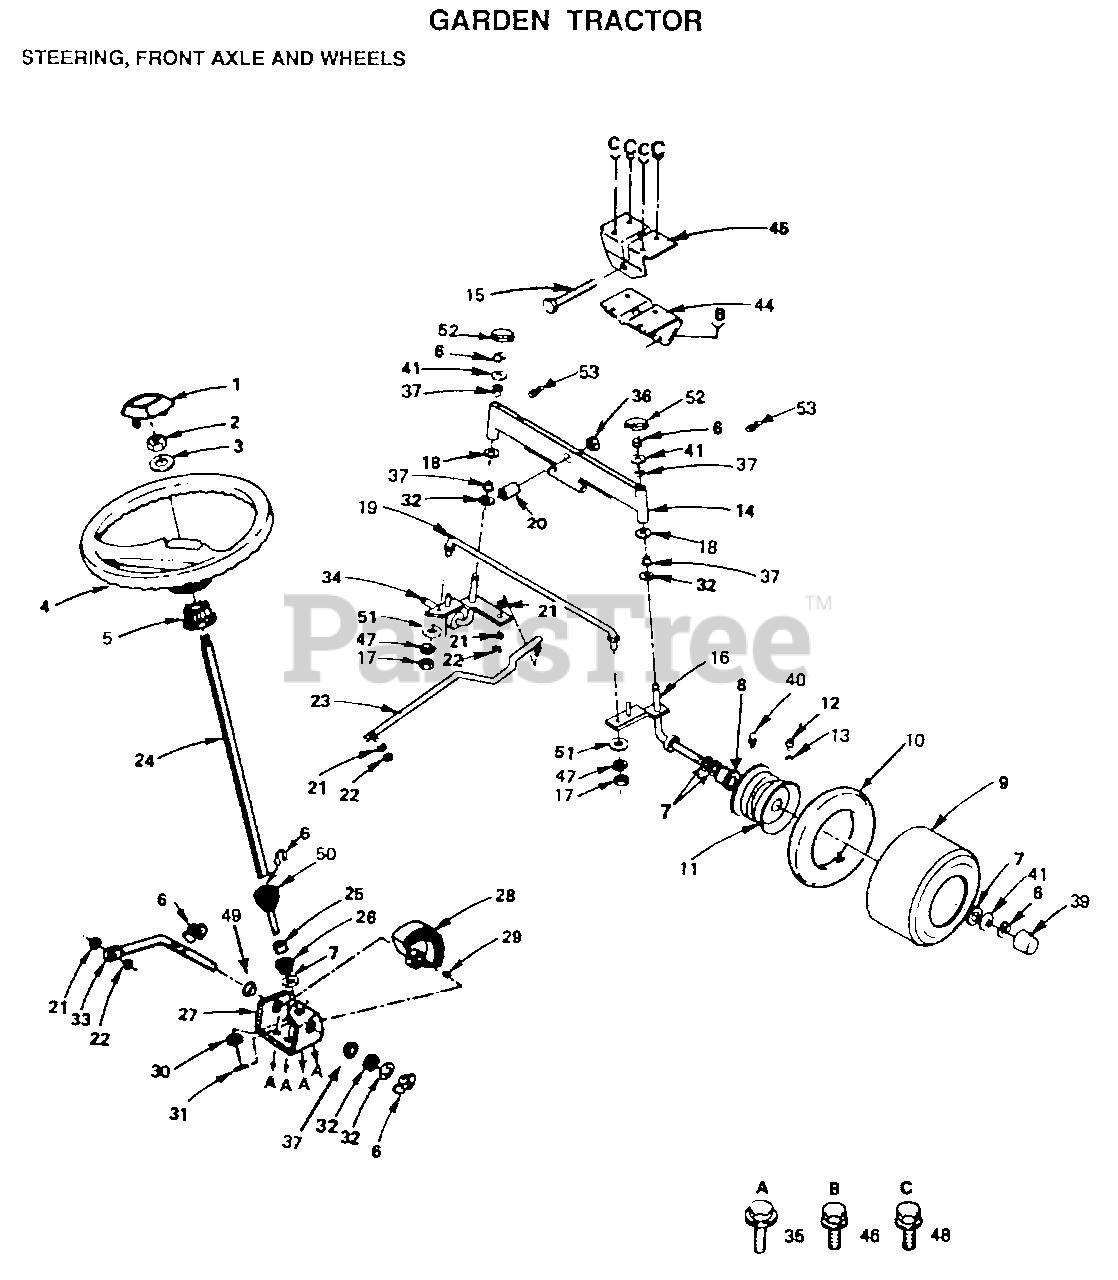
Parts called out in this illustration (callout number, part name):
3	WASHER
5	ADAPTER LT
6	RING
7	WASHER
8	"FLANGE, BEARING"
10	TUBE.5.3/4.5/6
12	VALVE STEM LT
13	VALVE CAP
14	FRONT AXLE
15	BOLT LT
17	NUT.LOCK.5/16-24
18	WASHER
19	ROD TIE
20	BEARING
21	LOCKWASHER
23	LINK-DRAG LT
24	STEERING SHAFT T
25	SHAFT SPACER LT
26	BUSHING
28	GEAR.SECTOR.HYT
29	KEY-WOODRUFF LT
32	WASHER .T
33	ROD STEERING T
34	SPINDLE-LH LT
35	SCREW
36	"NUT-LOC,FLANGE LT"
37	COL. SRTG. BEAR.
39	HUB CAP
40	FITTING LT
41	WASHER
44	SUPPORT.SADDLE.FT
45	SUPPORT-SADDL T
46	SCREW LT
47	LOCKWASHER
48	SCREW SPECIAL
49	NYLINER T
50	GEAR PINION T
51	WASHER M
52	CAP
53	ZERK M
